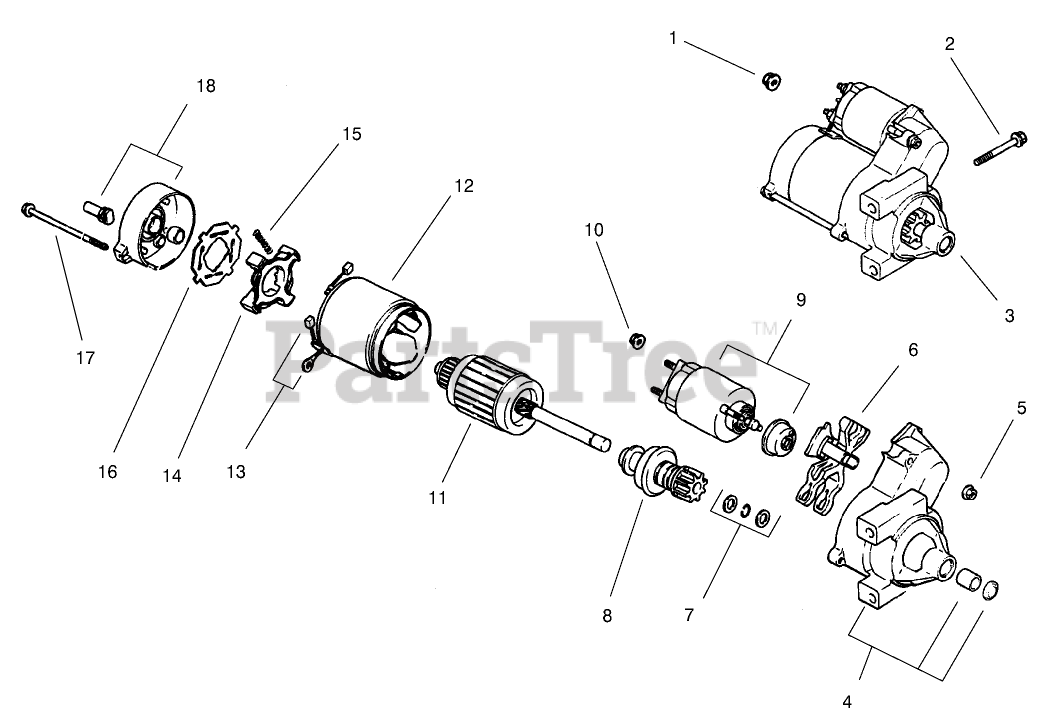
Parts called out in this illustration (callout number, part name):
1	NUT-FLANGE (M8X1.25)
2	SCREW-FLG (M8X1.25X80)
3	Starter, solenoid shift assembly (Incl. 4-18)
4	Cap-End, Drive
5	Nut-Starter
6	LEVER-DRIVE, STARTER
7	STARTER REPAIR KIT
8	Drive-Pinion
9	Solenoid
10	Nut
11	Armature-Starter
12	Frame w/Brushes ASM
13	Kit, brush & spring (Includes 15)
14	Holder-Brush
15	Spring-Brush
16	Insulator
17	Bolt-Thru
18	Commutator-cap, end
